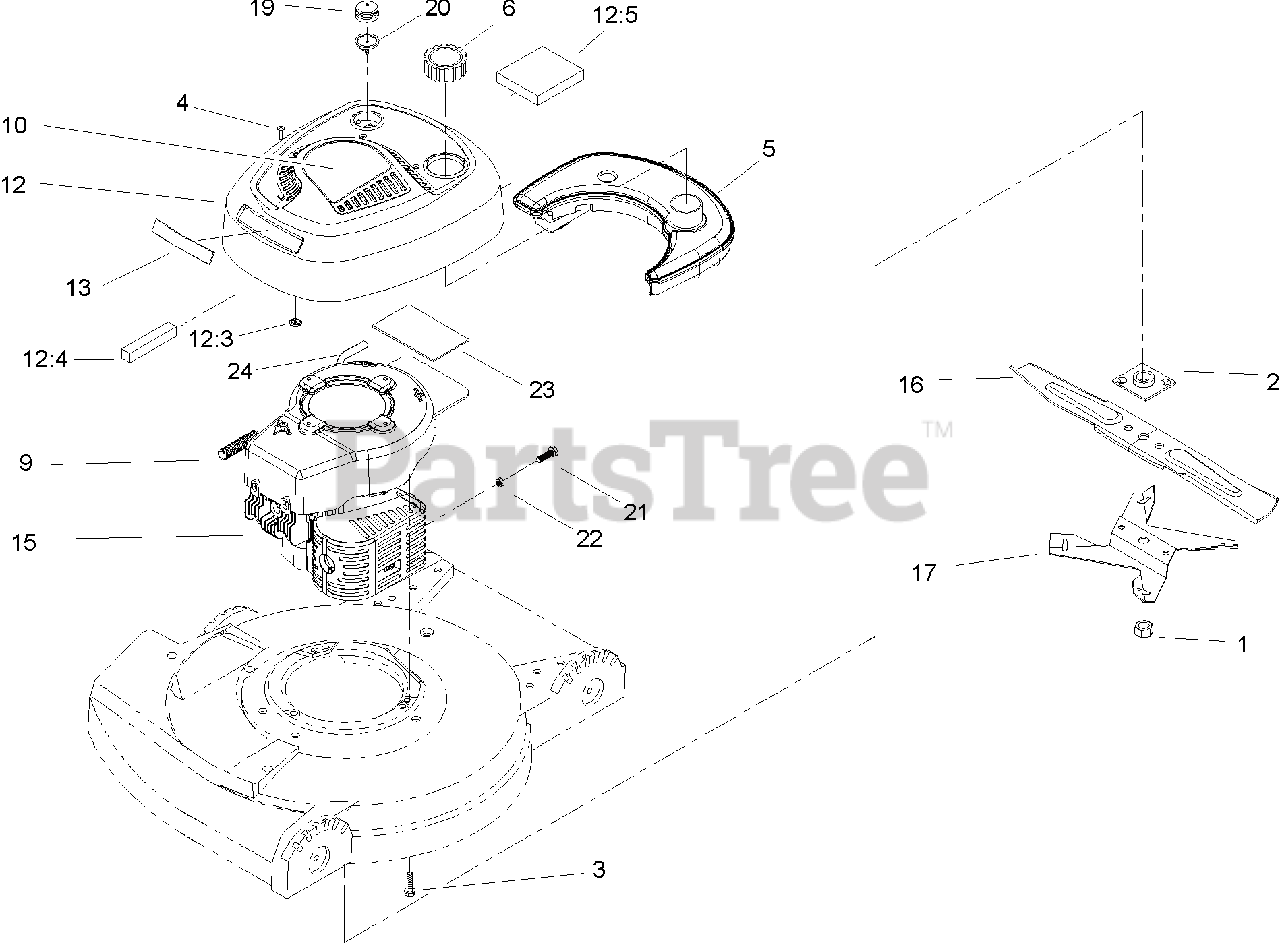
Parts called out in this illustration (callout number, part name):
1	NUT-BLADE
2	PLATE AND COLLAR ASM
3	SCREW-HH, SEMS
6	FUEL AND OIL CAP ASM
9	SPRING-COMPRESSION
10	DECAL-RECOIL
12	SHROUD AND RECOIL COVER ASM
12:3	NUT-PUSH
12:4	STRIP-FOAM
12:5	STRIP-FOAM
13	APPLIQUE-SHROUD
15	Engine ASM
17	FAN-MULCHING
19	BULB-PRIMER
20	BODY-PRIMER
22	NUT-HEX
23	PAD-FOAM
24	LINE-FUEL
